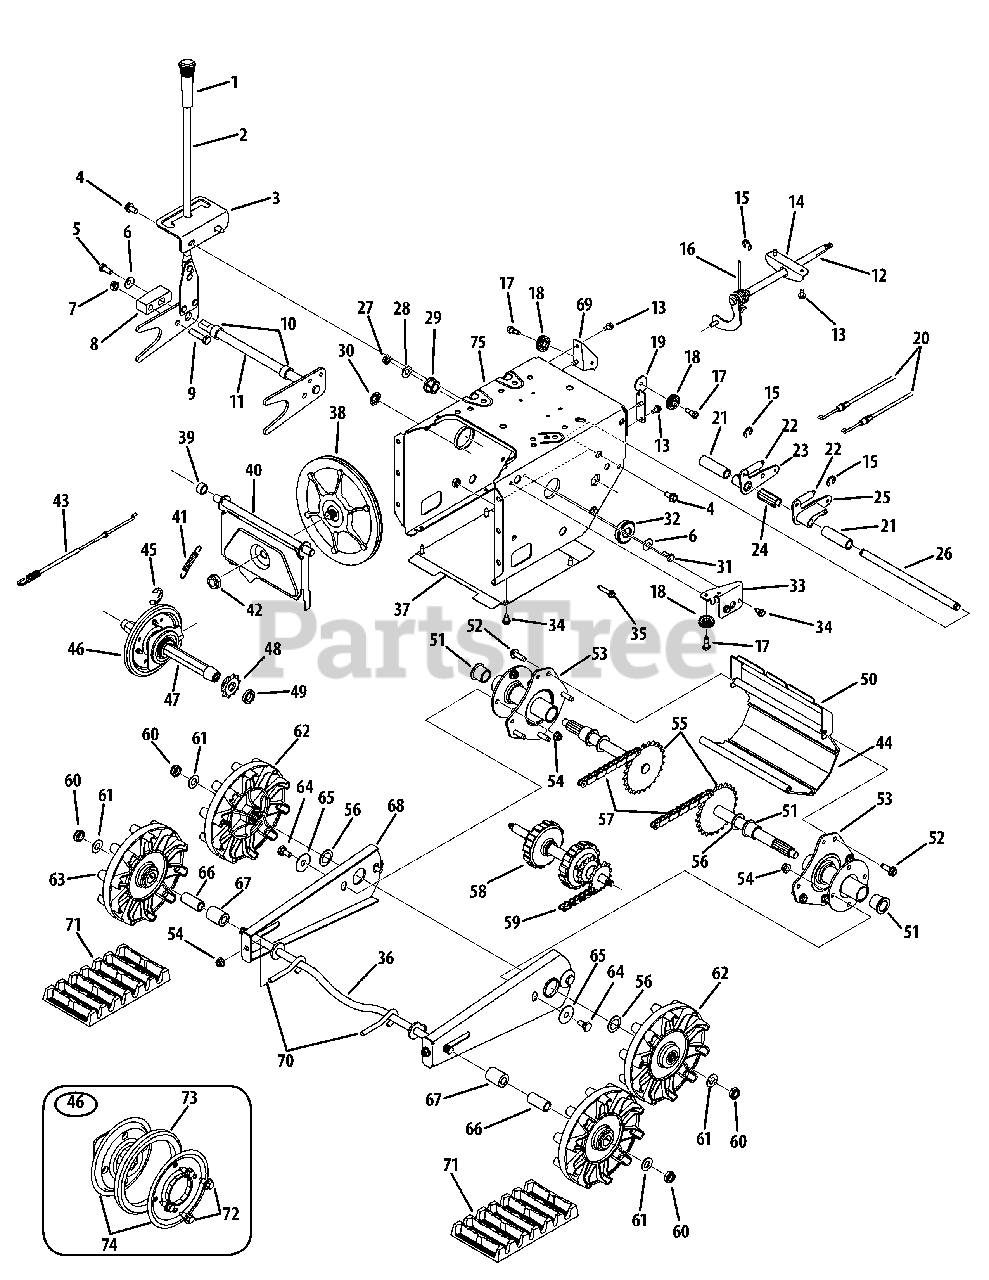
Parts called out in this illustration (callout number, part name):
1	Grip, .5 ID x 3.45
4	Hex Washer Screw, 5/16-18 x .750
5	Hex Screw, 5/16-24 x .75
6	Bell Washer, .340 x .872 x .060
7	Hex Lock Nut, 3/8-16
8	Lift Shaft Drive
9	Hex Screw, 3/8-16 x 1.50
10	Spacer, .828 ID x .875 OD x .500
12	Shift Rod Assembly
13	Hex Washer Screw, 1/4-20 x .500
16	Torsion Spring, .750 ID x .968
17	Shoulder Screw, .34 x .335 x 1/4-28
18	Cable Roller
19	Auger Cable Guide Bracket
20	Track Steering Cable
21	Spacer, .515 x 735 x 2.44
22	Extension Spring, .48 OD x 2.03
23	Dogg Assembly, RH
24	Spacer, .491 ID x 1.87
25	Dogg Assembly, LH
26	Shift Actuator
27	Jam Lock Nut, 3/8-24
28	Flat Washer, .406 x .875 x .059
29	Hex Flange Bearing
30	Speed Nut, .500
31	Hex Lock Screw, 5/16-18 x .625
32	Ball Bearing
33	Auger Cable Support Guide
34	Hex Washer Screw, 1/4-20 x .625
35	Hex Washer Screw, 1/4-20 x 1.000
37	Track Frame Cover
38	Friction Wheel Disc Assembly
39	Spacer, .525 ID x .750 x .42
40	Friction Wheel Support Bracket
41	Extension Spring
42	Flange Nut, 5/16-18
43	Drive Clutch Cable
46	Friction Wheel Assembly
47	Hex Track Shaft
48	Sprocket, 10T
49	Spacer, .675 ID x 1.00 OD x .23
52	Hex Washer Screw, 5/16-18 x 1.0
53	Track Hub Assembly
54	Flange Lock Nut, 5/16-18
55	Track Axle Assembly
56	Flat Washer, .793 x 1.24 x .06
58	Drive Track Shift Assembly
60	Jam Lock Nut, 1/2-20
61	Flat Washer, .510 x 1.00 x .060
62	Track Drive Wheel
63	Track Idler Wheel
64	Shoulder Screw, .43 x .56 5/16-18
65	Flat Washer, .442 x 1.38 x .060
66	Spacer, .51 ID x .75 OD x 1.67
67	Spacer, .510 ID x 1.0 OD x 1.34
69	Drive Cable Guide Bracket
70	Eye Bolt, 5/16-18 x 3.0
71	Snow Trac
72	Hex Washer Screw, 1/4-14 x .625
73	Friction Wheel
74	Friction Plate
75	Frame Assembly
